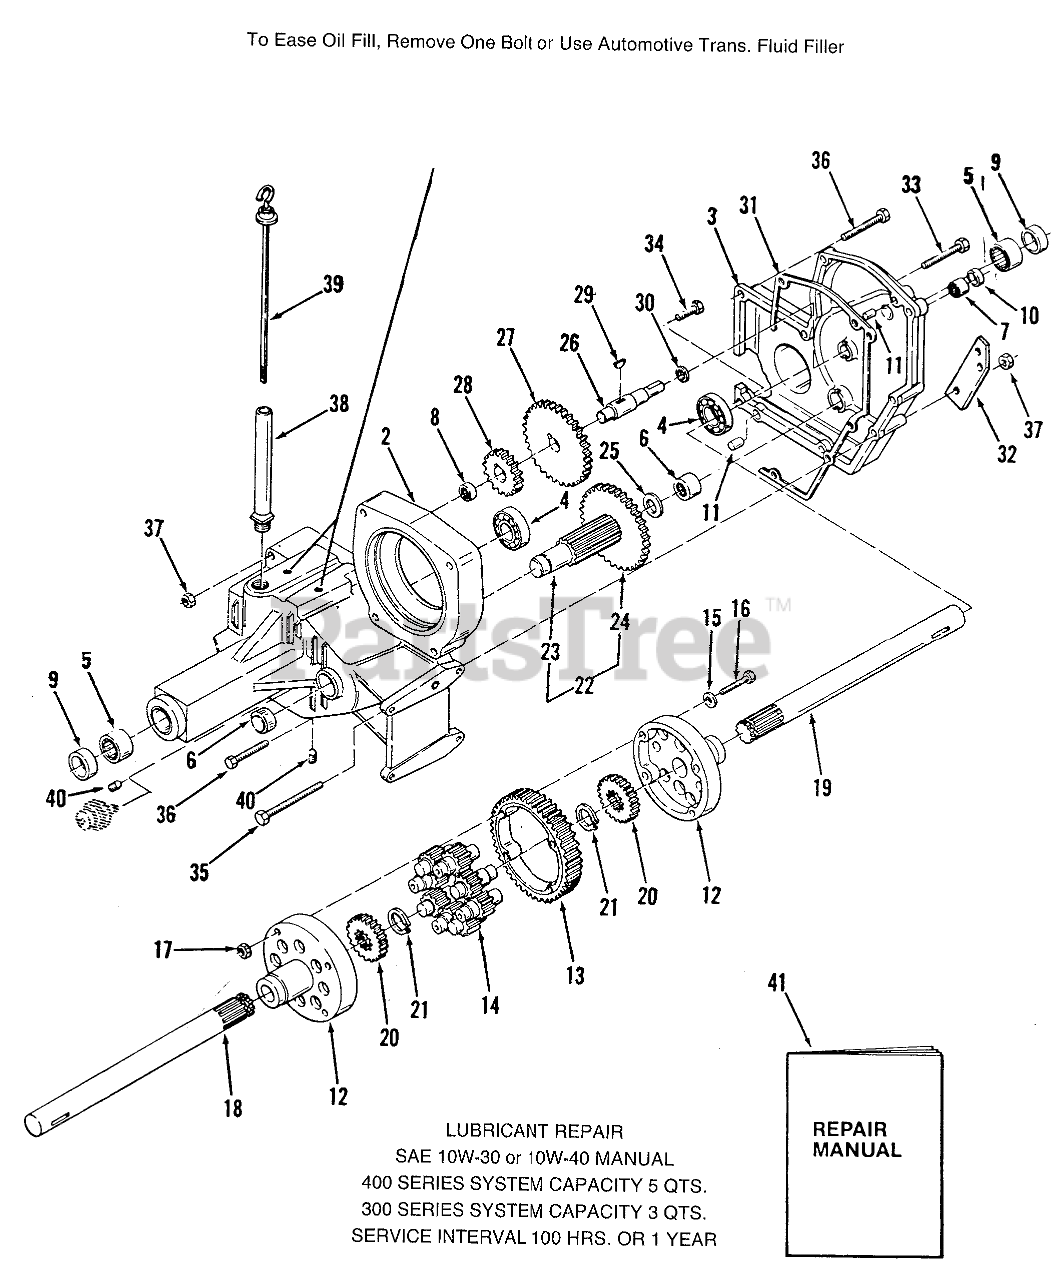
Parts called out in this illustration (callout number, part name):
2	CASE-TRANS RH
3	CASE TRANS LH
4	BEARING-BALL
5	BEARING
6	BEARING-NEEDLE
7	NEEDLE BEARING
8	BEARING-NEEDLE
9	SEAL-OIL
10	Seal
11	PIN-LOCATING
12	END CAP-DIFFERENTIAL
13	GEAR-DIFFERENTIAL RING, 43T
14	GEAR-PINION, 11T
15	WASHER
16	BOLT-HEX
18	AXLE-REAR RH
19	AXLE-REAR LH
20	GEAR-AXLE DIFFERENTIAL
21	RING-SNAP
22	ASSY GEAR
23	PINION SHAFT
24	GEAR 46T
25	WASHER-THRUST
26	SHAFT GEAR
27	GEAR 46 TEETH
28	GEAR 20 TEETH
29	Key
30	Race Thrust
31	GASKET-TRANSMISSION
32	BRACKET-BRAKEB
33	Bolt
34	Bolt
35	Hex Bolt
36	Screw-Hex. Hd.
37	Nut
38	NIPPLE-TRANS FILL
39	Dipstick
40	PLUG 1/4 PIPE ALLEN
41	Repair Manual
